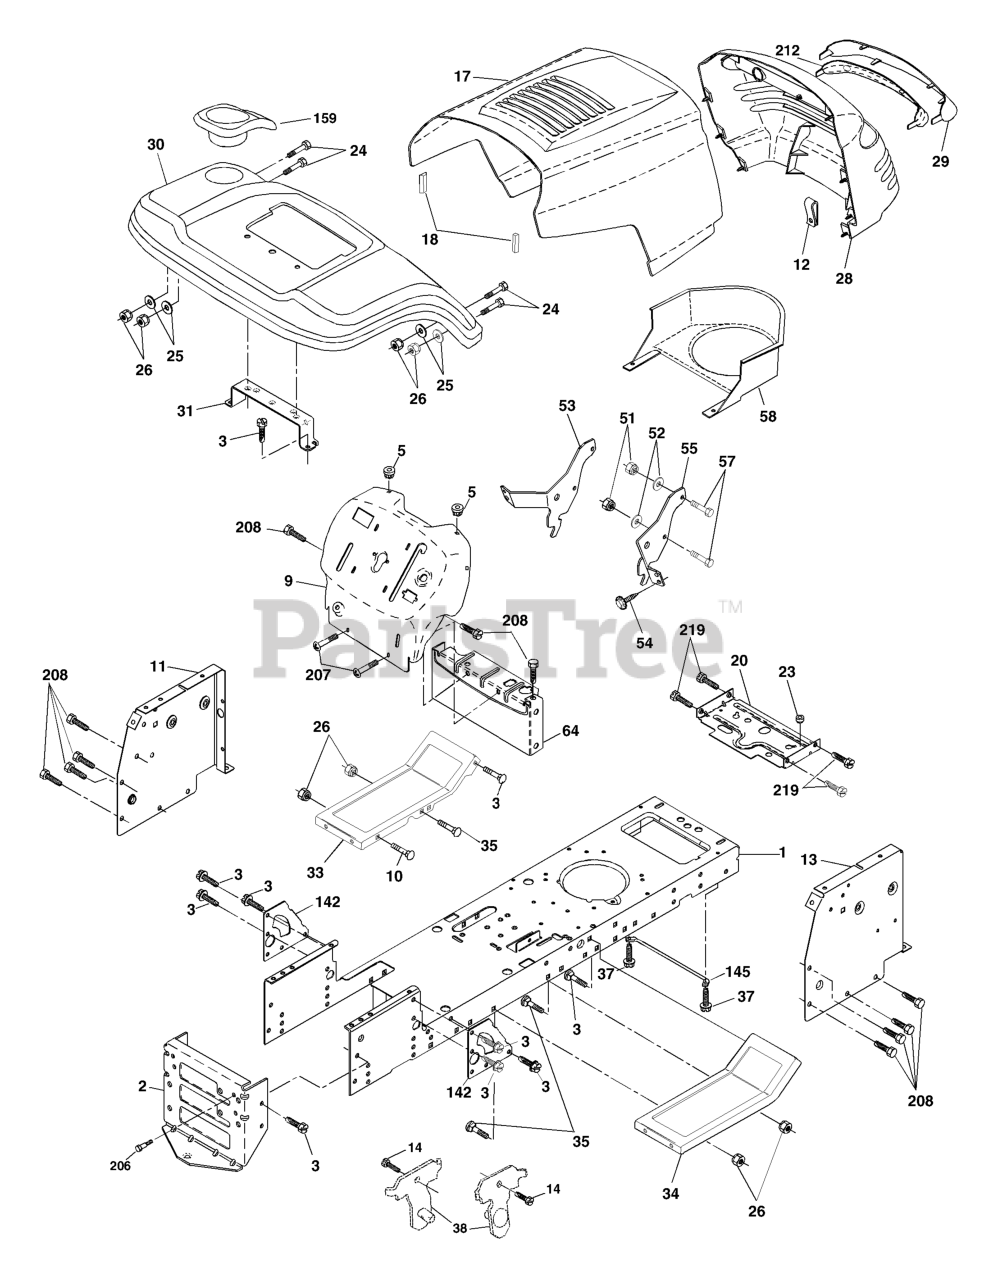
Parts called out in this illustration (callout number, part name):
1	CHASSIS STAMPING
2	DRAWBAR, 12GA
3	SCREW 3/8-16X3/4
5	BUMPER.RUBBER.HOOD
9	DASH(SUBS)
10	BOLT D
11	PANEL.DASH.LH.LTX
13	PANEL DASH RH
14	SCREW LT
17	HOOD ASM.
18	BUMPER HOOD T
20	PLATE MTG.BATTERY/FUEL TANK
23	BUSHING.SNAP.NYL.BLK.
24	BOLT
25	WASHER
26	NUT
28	GRILLE/LENS ASM
29	LENS
30	FENDER, YTH1746
31	BRACKET FENDER
33	FOOTREST PNT LH
34	FOOTREST PNT RH
35	BOLT
37	Screw Thdrol 6/16-18 x 1/2 TYT
38	BRACKET.ASM.PIVOT.MOWER.REAR
51	LOCKNUT.NYLOC.1/4-20
52	WASHER
53	BRACKET.GRILLE.LH
54	SCREW.HEX.WS.HD.8-18 X 7/8
57	BOLT
58	AIR DUCT P/L/LT
64	DASH LOWER
142	PLATE REINFORCEMENT
145	ROD PIVOT CHASSIS/HOOD
159	CUPHOLDER
206	SHOULDER BOLT 5/16-18TT
207	SCREW, 5/16-18 X 1/2
208	SCREW 3/8-16X1/2
212	REPL BY 532 1745-03
219	SCREW
